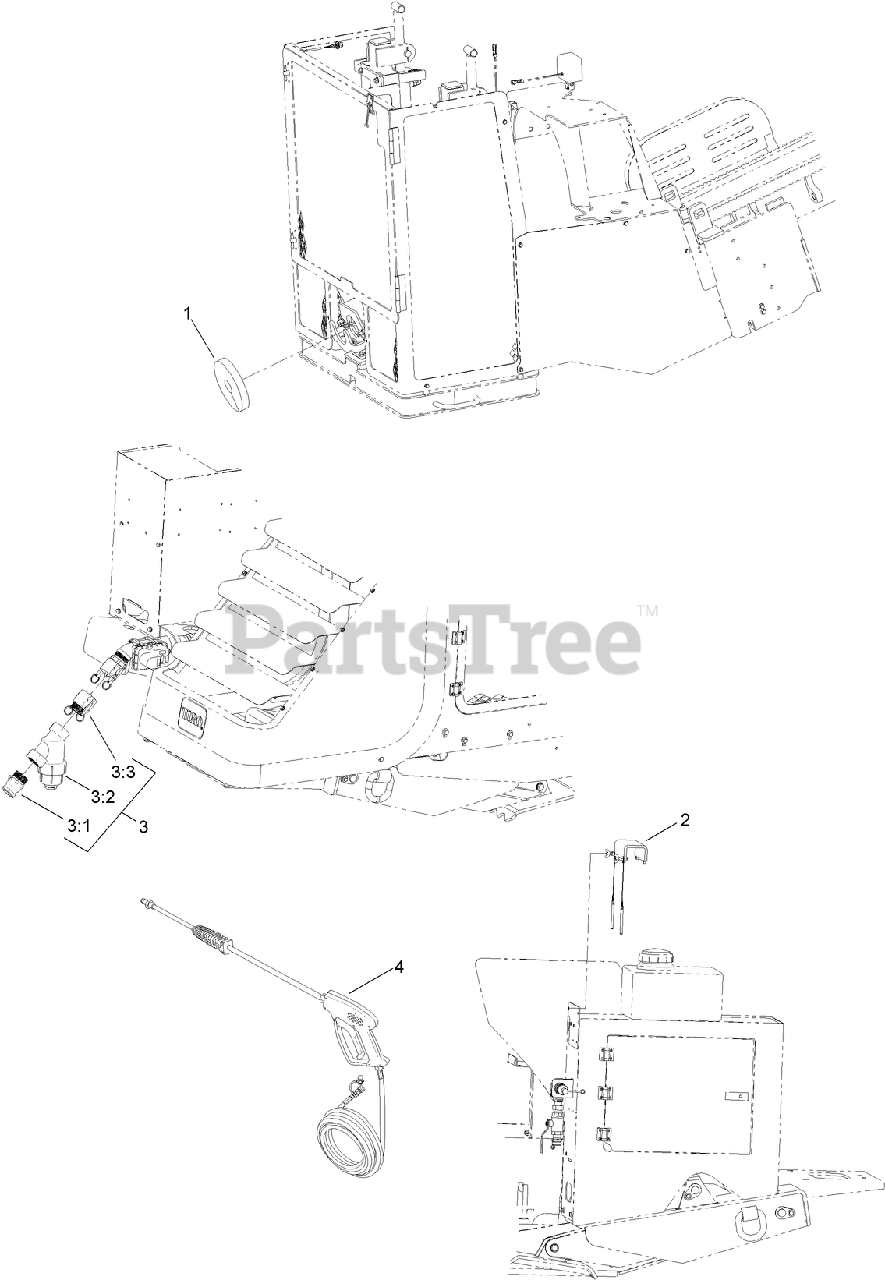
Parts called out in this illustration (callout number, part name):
1	WIPER-SPLIT
2	CYLINDER LOCKOUT ASM
3	STRAINER KIT
3:1	ADAPTER-MALE
3:2	STRAINER-Y
3:3	FITTING-CAMLOK
4	WASH DOWN WAND ASM
